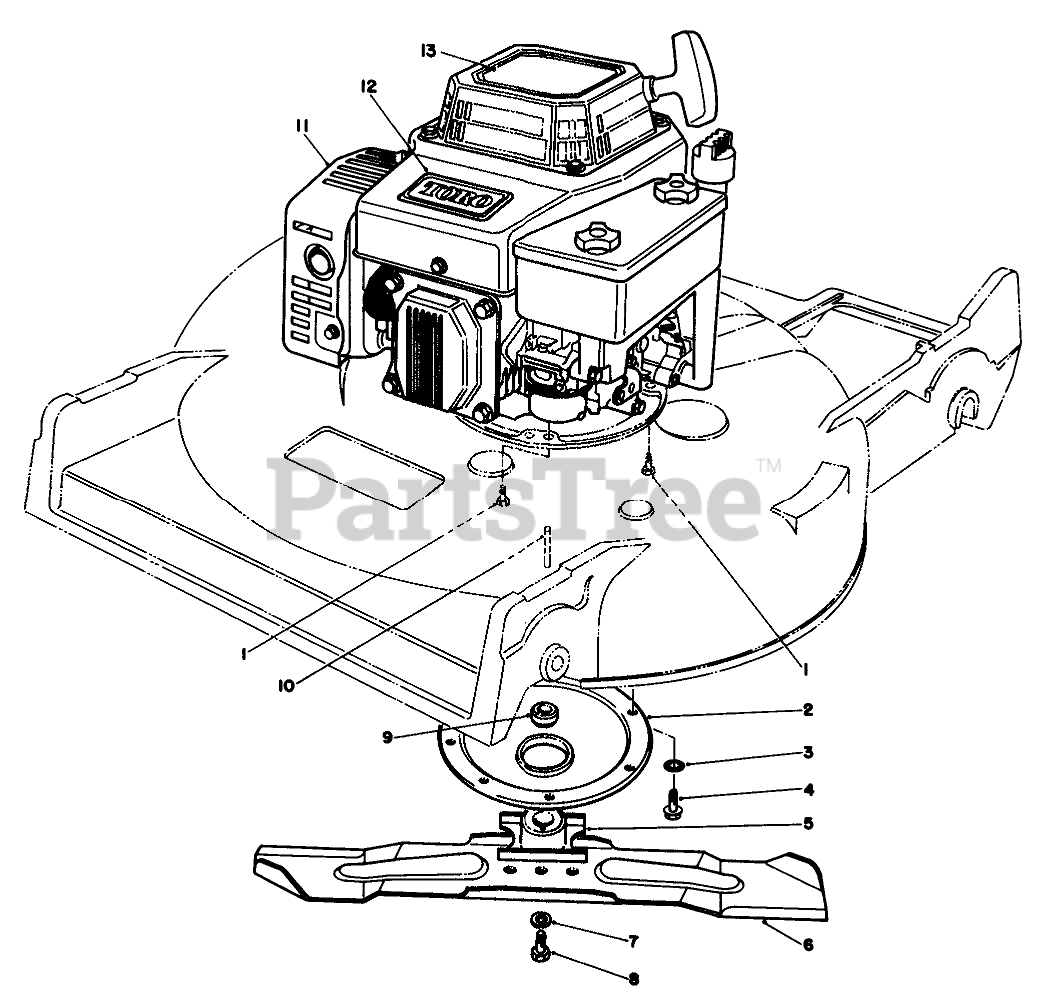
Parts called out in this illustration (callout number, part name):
1	SCREW-HWHTF
2	PROTECTOR-CRANKSHAFT
3	WASHER-LOCK, INTERNAL
4	SCREW-HWHTF
5	RETAINER-BLADE
6	BLADE-21in
7	WASHER-LOCK
8	SCREW-BLADE
9	SPACER-BLADE RETAINER
10	KEY-SQUARE
11	Engine
12	Plate-Logo
13	LOGO PLATE - RECOIL
